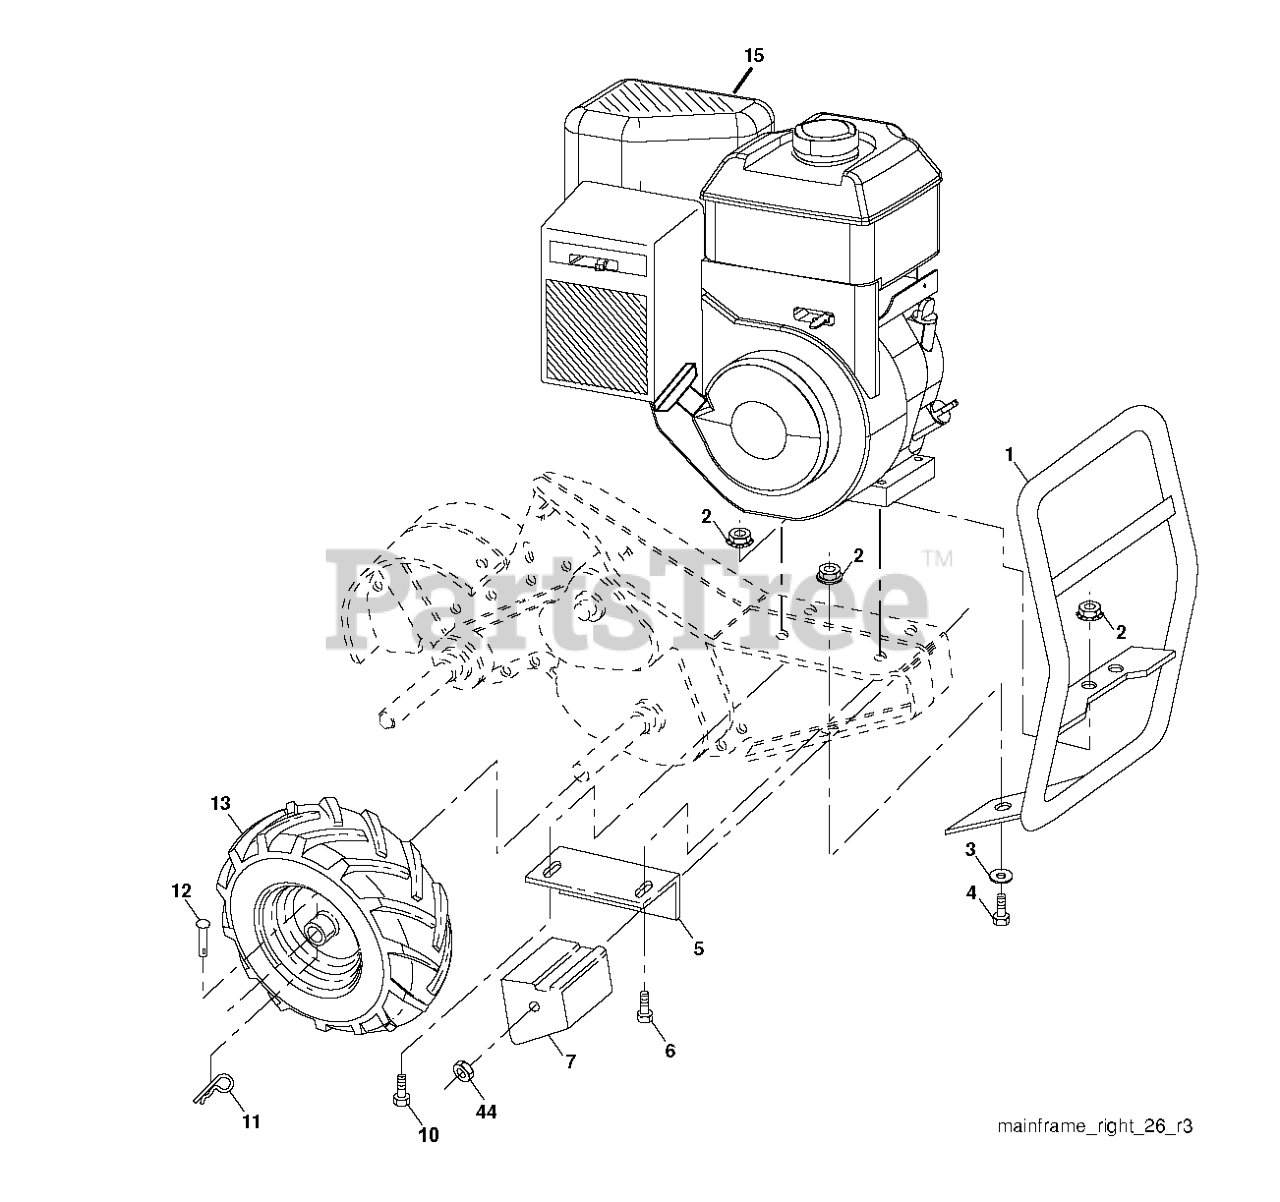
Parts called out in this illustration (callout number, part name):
1	RP.BUMPER.ASM.TILLER.
2	LOCKNUT-FLANGE 5/16-18
3	WASHER
4	BOLT
5	DNO BRACKET RH CRT
6	BOLT, HEX 5/16-18X1-3/4
7	COUNTERWEIGHT, RH
10	BOLT
11	RETAINER M
12	RIVET,DRILLED
13	TIRE.13X5-6.CHEVRON.TILLER
13	RIM.ASM.6".SILVER
13	VALVE STEM LT
